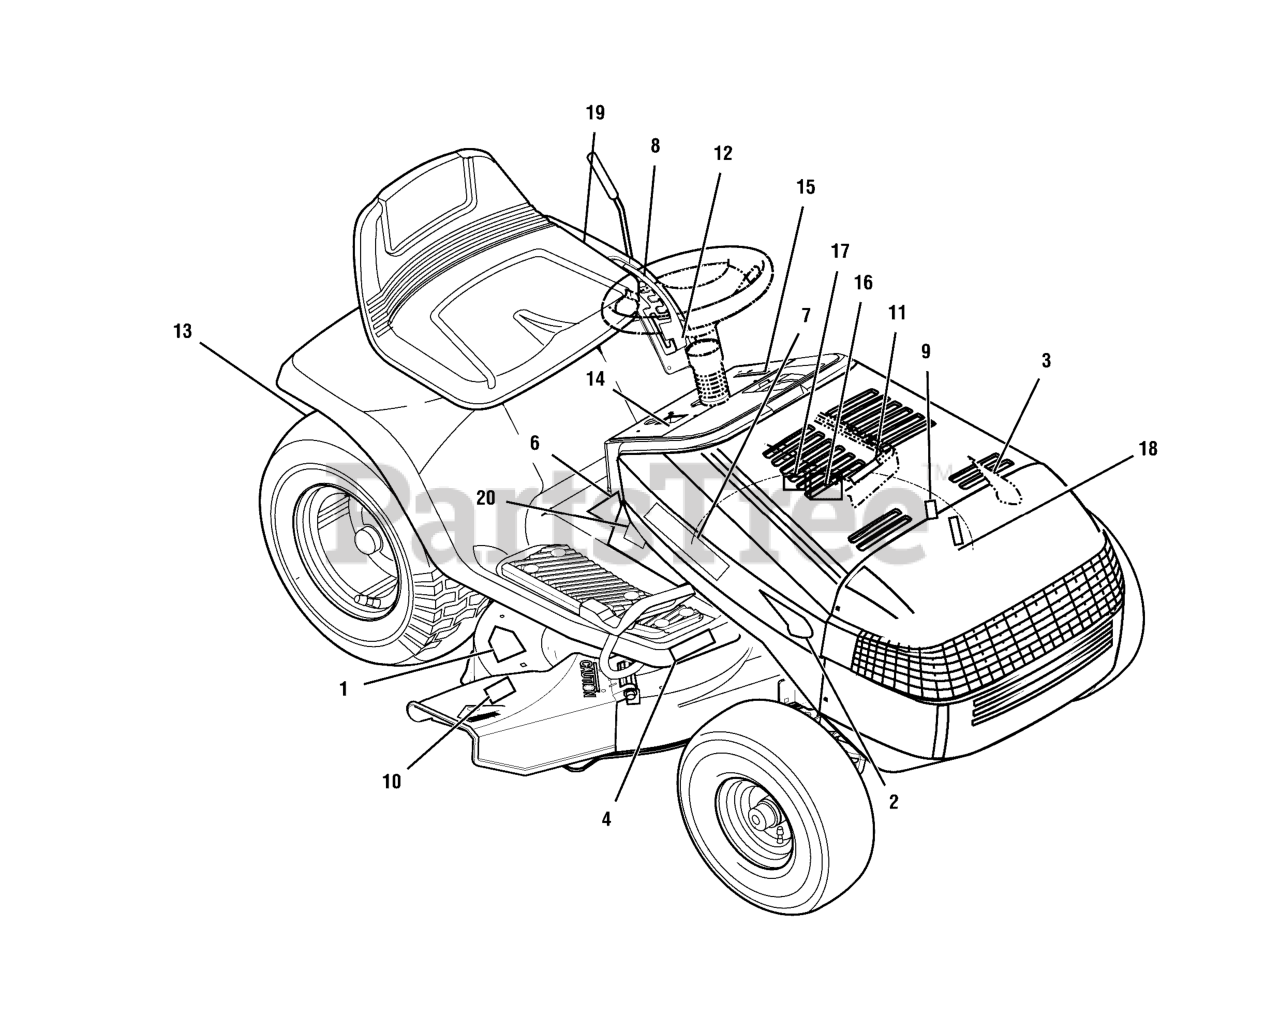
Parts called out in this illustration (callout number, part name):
1	DECAL, ENGLISH CUT FINGER
2	DECAL, MASPORT 20.0/42 RH
3	DECAL, MASPORT 20.0/42 LH
4	DECAL, 6 SPD LARGE SEAT DK
6	DECAL, WARNING
7	DECAL, MASPORT LOGO
8	DECAL, 1/6 HGT ADJUST LIFT LGSD
9	DECAL, NO STEP LH HSNG
10	DECAL, NO STEP CHUTE
11	DECAL, BRAKE/PARK BRAKE
12	DECAL, DECK LEVEL POS/ONLY
13	DECAL, WARNING LOAD LMT
14	DECAL, IGNITION ENGAGE PRK BRK (NMR)
15	DECAL, THROTTLE TWIN
16	DECAL, GAGE WHEEL INST
17	DECAL, GAGE WHEEL, LEVELING
18	DECAL, 3 WAY
19	DECAL, ENGAGE PTO
20	DECAL, V2-SS-1X3 CUTTING HEIGHT
